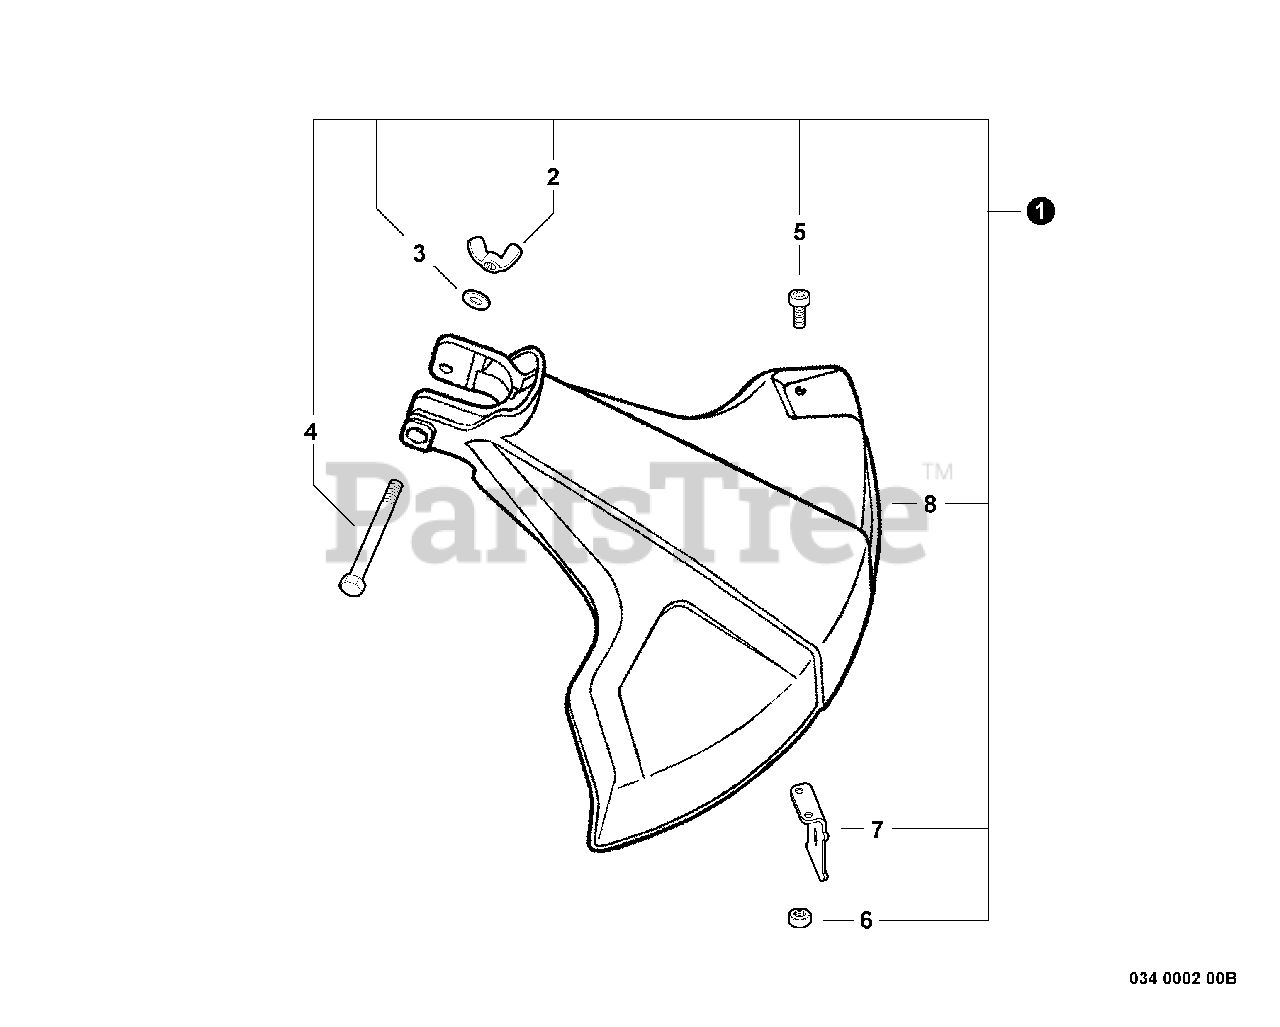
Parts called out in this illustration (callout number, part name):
1	DEBRIS SHIELD KIT
2	WINGNUT - 1/4-20
3	WASHER - 1/4"
4	BOLT - 1/4-20 X 2"
5	SCREW - 5X12
7	KNIFE, TRIMMER LINE
8	SHIELD, DEBRIS - PLASTIC
